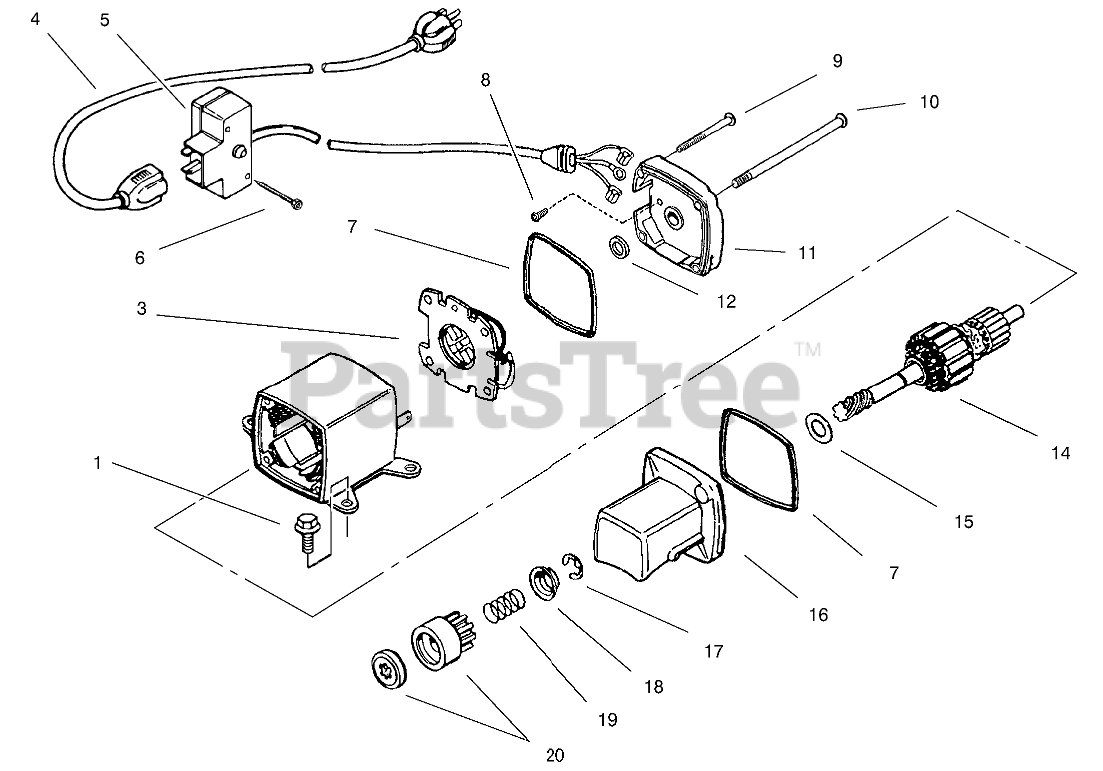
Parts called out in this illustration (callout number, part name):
1	Screw (T-30, 1/4-20 x 23/32)
3	Brush Card ASM
4	Cord-Extension (10-6)
5	Switch Box Asm (Incl. Ref. # 6)
6	Screw
7	O-Ring
8	Screw-Ground
9	Screw-Ground
10	Bolt-Case
11	Cap-Commutator End Asm (Incl. Ref. #7)
12	Washer-Thrust
14	Armature
15	Washer-Thrust
16	Cap-Drive End (Incl. Ref.# 7)
17	Retainer-Ring
18	Retainer-Spring
19	Spring-Anti Drift
20	Nut & Gear
